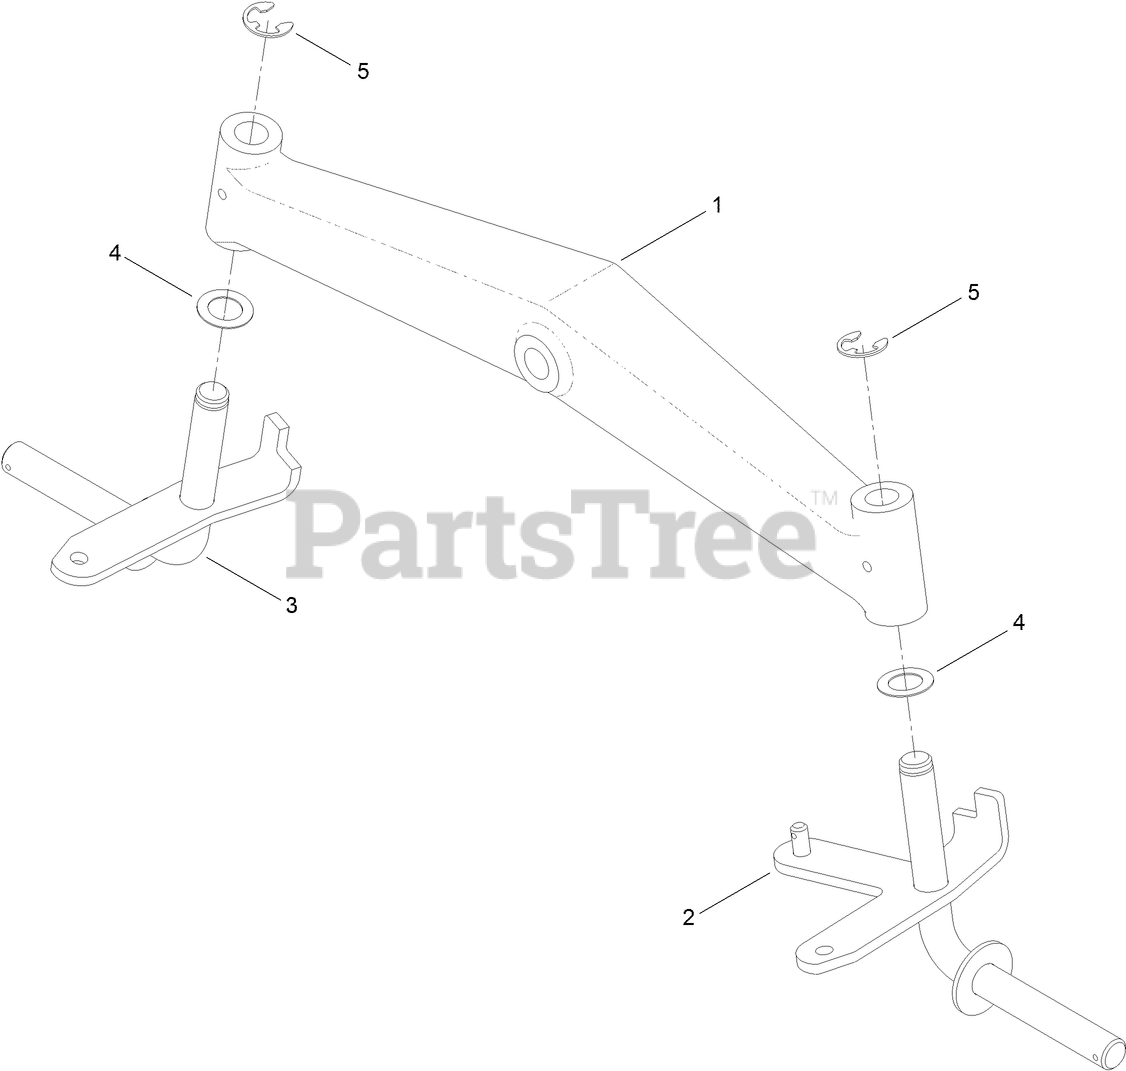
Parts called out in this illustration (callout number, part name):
1	AXLE-FRONT
2	SPINDLE-LH
3	SPINDLE-RH
4	WASHER-THRUST
5	E-RING
